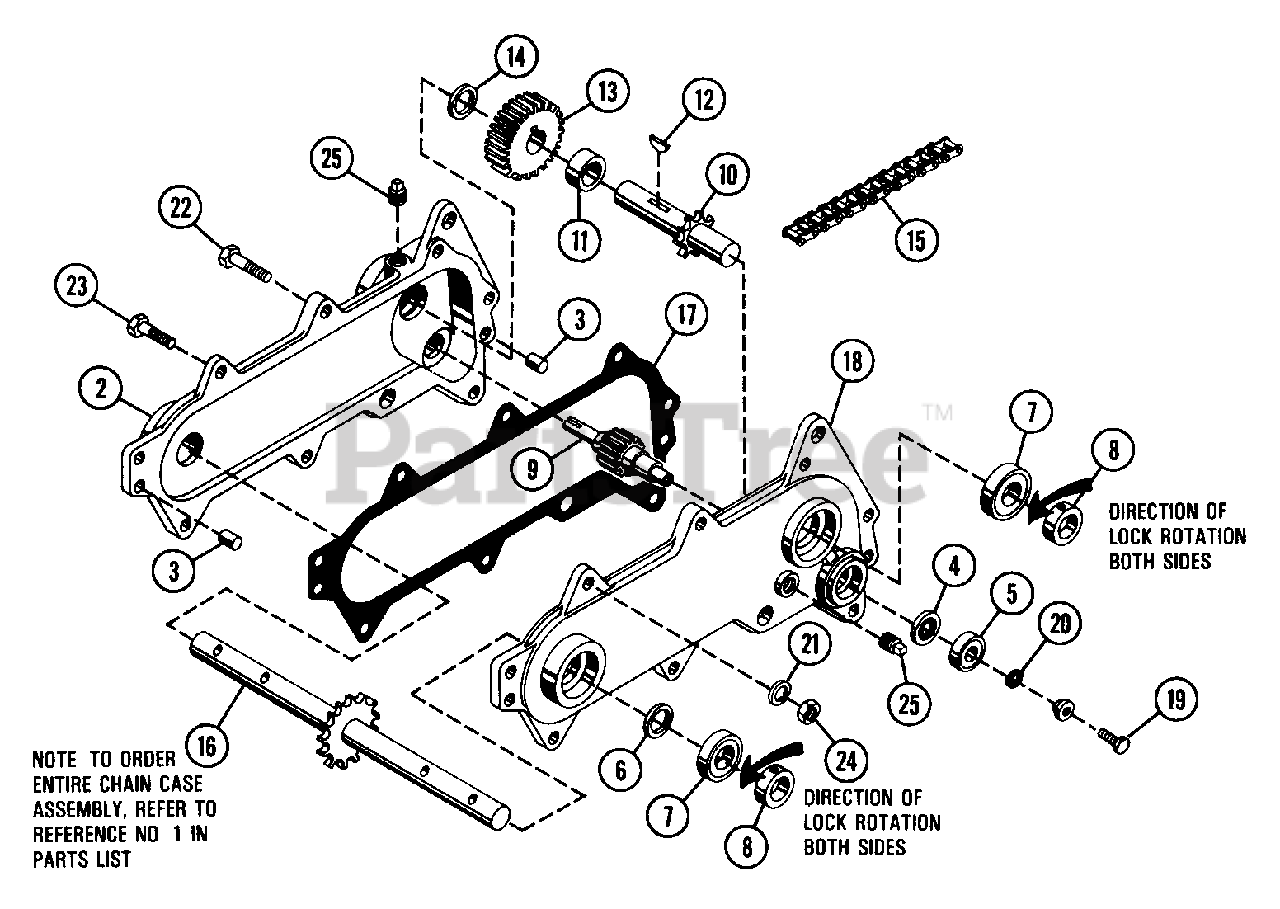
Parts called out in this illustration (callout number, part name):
1	CHAIN CASE ASSEMBLY
2	CHAIN CASE
3	DOWEL PIN
4	SEAL 1.00X1.50X.188
5	BRG-BALL .750X1.781X.61
6	SEAL 1.125X1.874X.250
7	BRG-BALL 1.125X2MMX18MM
8	COLLAR-BEARING
9	DRIVE SHAFT
10	DRIVEN SHAFT
11	SPACER 1.137X1.50X.656
12	KEY-WDRF .25X1.00X.438 SAE15
13	GEAR 47T
14	SPACER 1.006X1.438X.467
15	ROLLER CHAIN #60 44P
16	TINE SHAFT
18	CHAIN CASE COVER
19	BLT-HEX .31-18X.75 PL GR5
20	WSHR-FL-STL .328X1.0X.094
21	WSHR-LK .312X.097 PL HVY
22	BLT-HEX .31-18X2.00 PL GR5
23	BLT-HEX .31-18X1.50 PL GR5
24	NUT-HEX .312-18
25	PIPE PLUG
